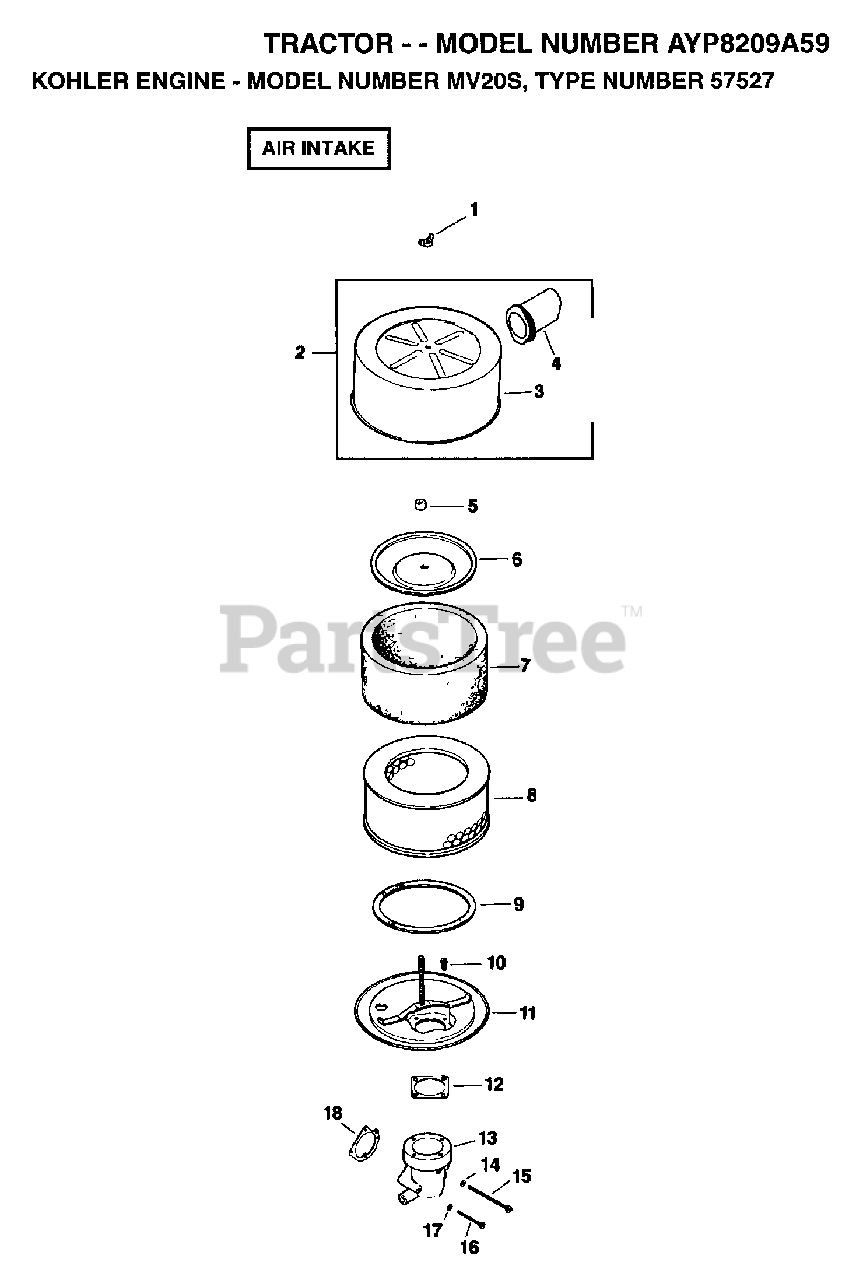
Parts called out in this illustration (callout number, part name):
3	COVER AIR CLEANER
4	TUBE AIR INTAKE
5	SEAL ELEMENT
6	COVER AIR CLEANER ELEMENT
13	ELBOW AIR INTAKE
18	GASKET, AIR CLEANER
